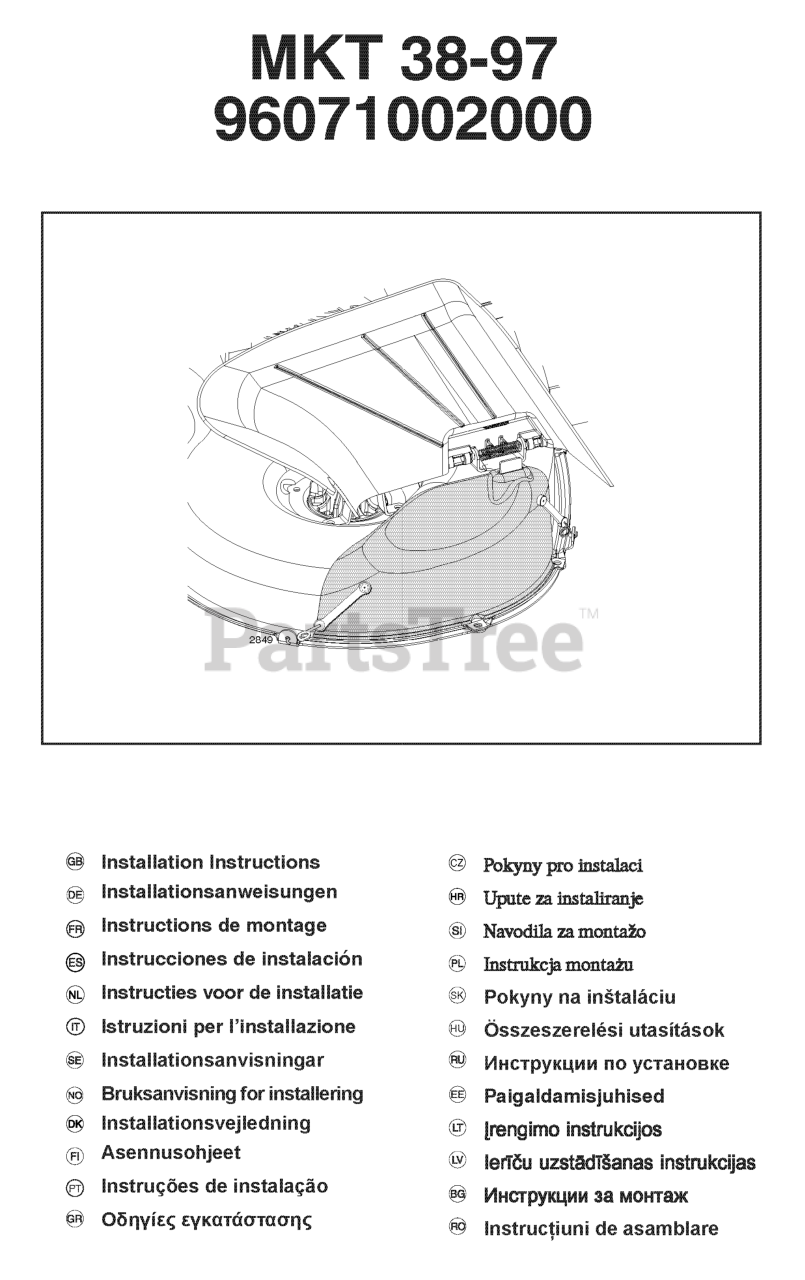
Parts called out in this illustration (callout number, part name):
1	BLADE 38" PREMIUM
2	Mulch Cover Assembly
3	LATCH ASSY
4	WELDNUT
6	LOCKWASHER #10
7	SCREW
